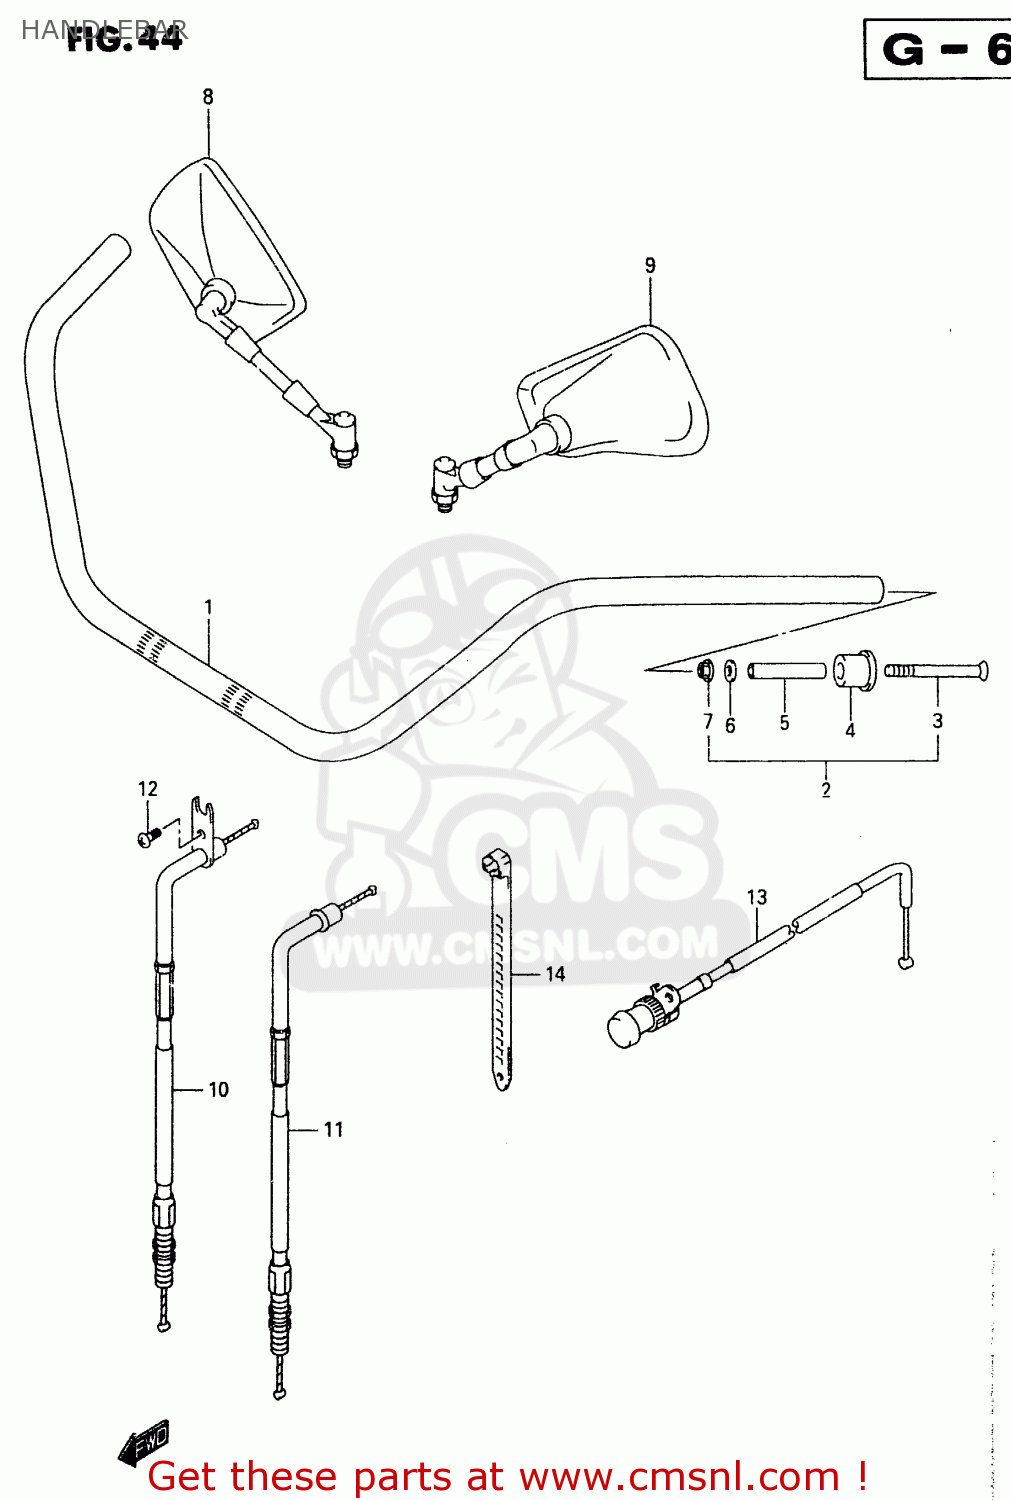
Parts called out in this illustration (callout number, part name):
1	HANDLEBAR
2	BALANCER SET,HANDLEBAR
3	SCREW(6X127)
4	EXPANDER,HANDLE BALANCER NO.2
5	SPACER,EXPANDER
6	WASHER (6.5X18X2)
7	NUT
8	MIRROR ASSEMBLY,REAR VIEW
9	MIRROR ASSEMBLY,REAR VIEW
10	CABLE ASSEMBLY,THROTTLE NO
11	CABLE ASSEMBLY,THROTTLE NO
12	SCREW
13	CABLE ASSY,STARTER
14	CLAMP(L:125)
